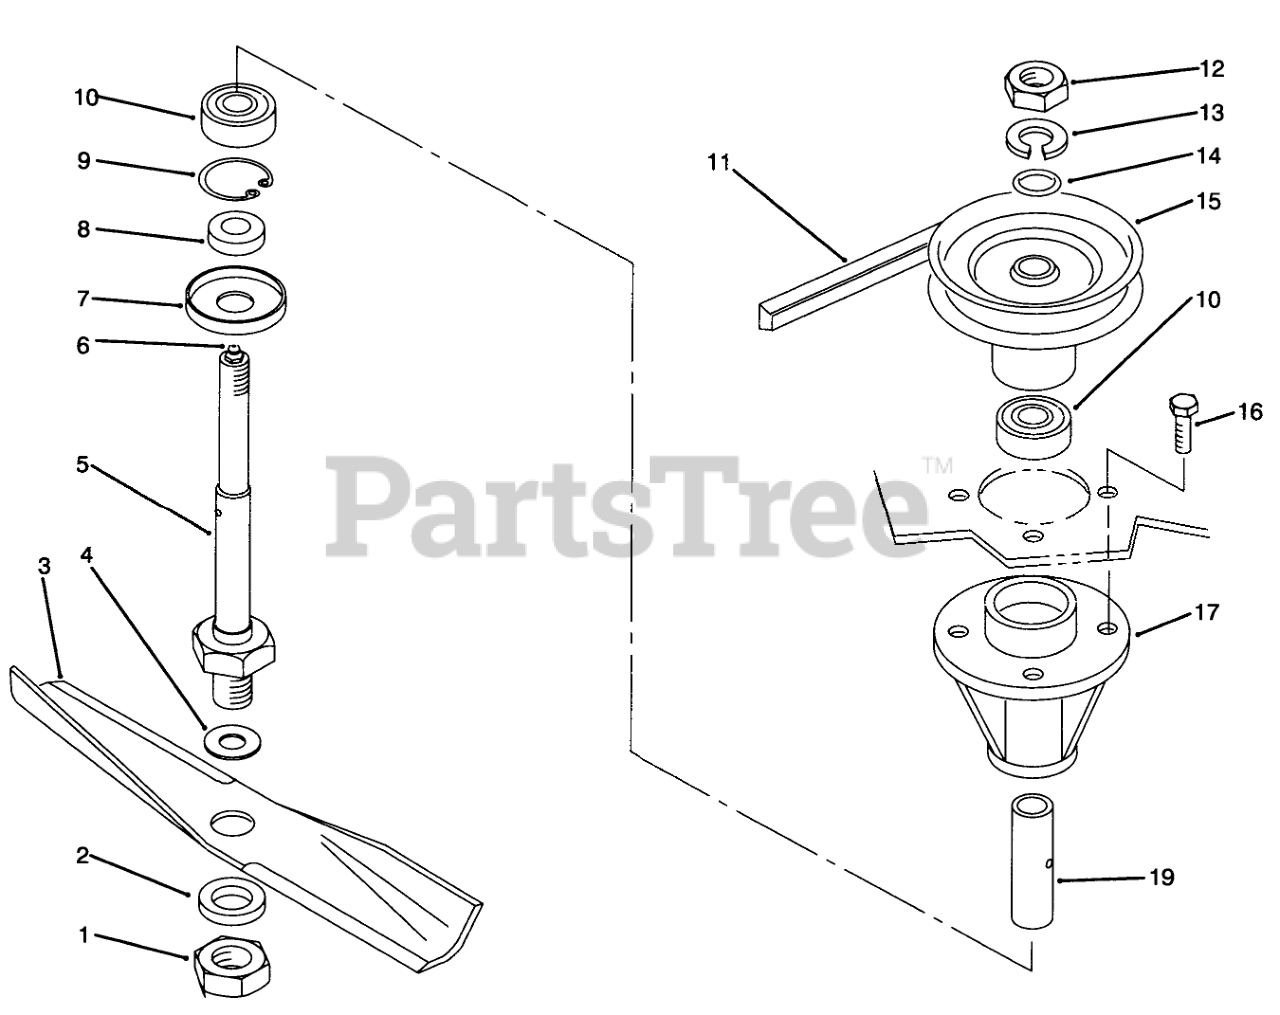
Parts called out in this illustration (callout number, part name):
1	NUT-JAM
2	WASHER-FLAT
3	14IN BLADE KIT
4	Washer
5	SHAFT-SPINDLE
6	FITTING-GREASE
7	CUP-SPINDLE
8	SPACER-BLADE
9	RING-RETAINING
10	BEARING-BALL
11	Belt
12	NUT-JAM
13	WASHER-LOCK
14	O RING
15	PULLEY
16	SCREW-HH
17	HOUSING-SPINDLE
